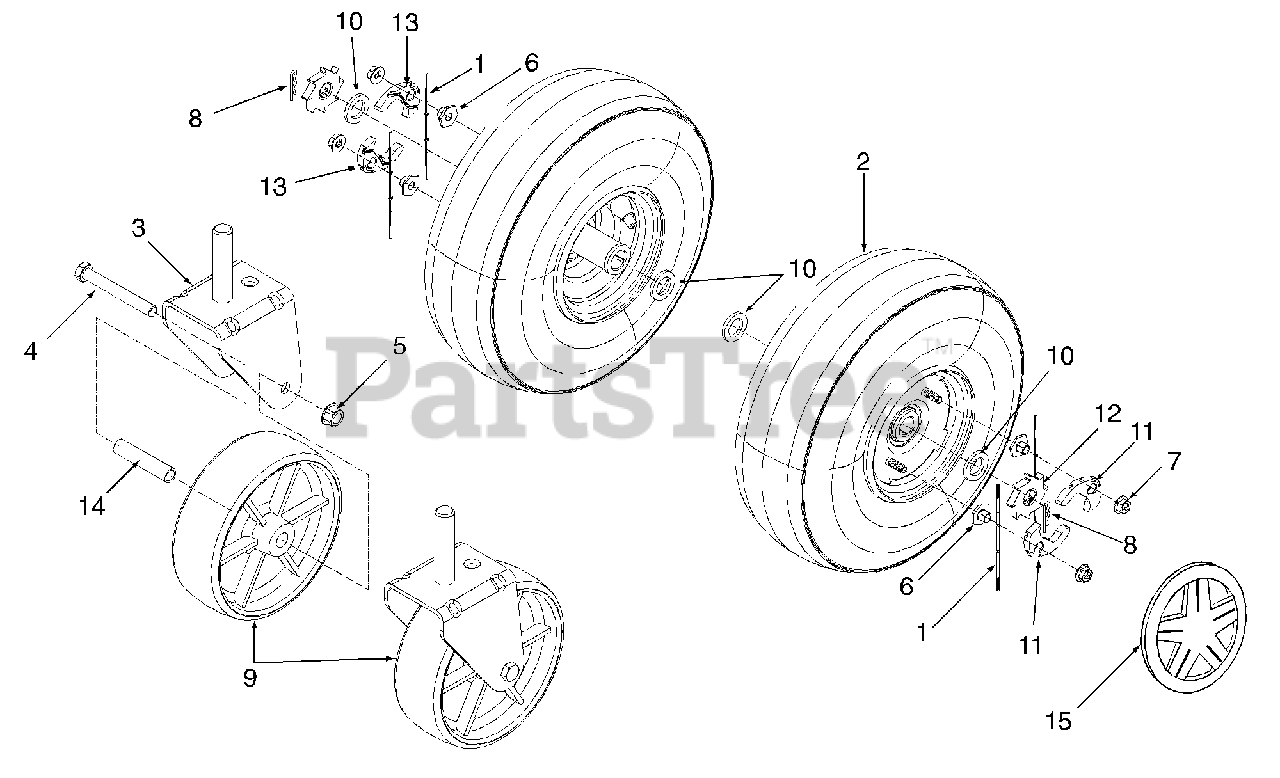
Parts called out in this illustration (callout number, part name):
1	Spring, Plastic Ratchet
3	Bracket Assembly, Pivot Wheel
4	Screw, Hex Cap, 3/8-16 x 3.0
5	Nut, Hex Flange Lock, 3/8-16
6	Nut, Special Hex 1/4-20
7	Nut, Hex Flange Lock, 1/4-20
8	Pin, Internal Cotter
9	Wheel, 6.00 x 2.00
10	Washer, Flat, .64 x 1.12 x .12
11	Pawl, LH .345 ID
12	Ratchet, Wheel, .5 Serr ID x 1.62
13	Pawl, RH .345 ID
14	Spacer, .384 ID x .5 OD x 2.3 Lg
15	Hubcap, 4.0 Yellow
